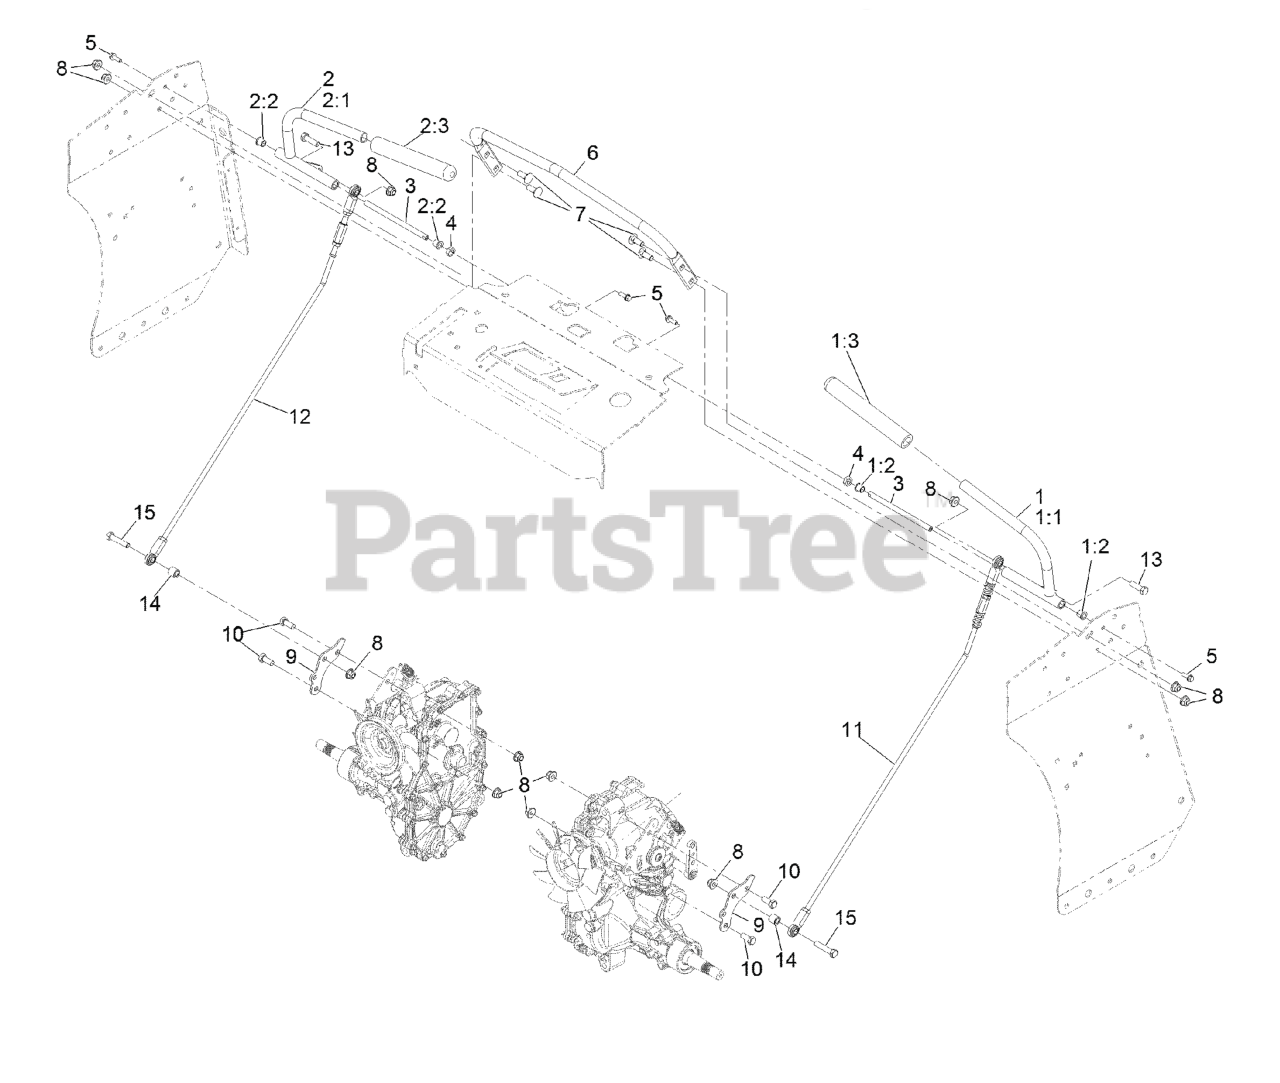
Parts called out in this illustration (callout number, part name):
1	LH Motion Handle ASM
1:1	HANDLE-CONTROL, LH
1:2	BEARING
1:3	GRIP-LEVER, CONTROL
2	RH Motion Handle ASM
2:1	HANDLE-CONTROL, RH
2:2	BEARING
2:3	GRIP-LEVER, CONTROL
3	SHAFT-PIVOT, MOTION CONTROL
4	SPACER-SHAFT, DRIVE LEVER
5	SCREW-HHF
6	BAR, REFERENCE
7	BOLT-CARR
8	NUT-HF, NI
9	ARM-MOTION
10	SCREW-HH
11	LH Motion Linkage ASM
12	RH Motion Linkage ASM
13	SCREW-HH
15	SCREW-HH
